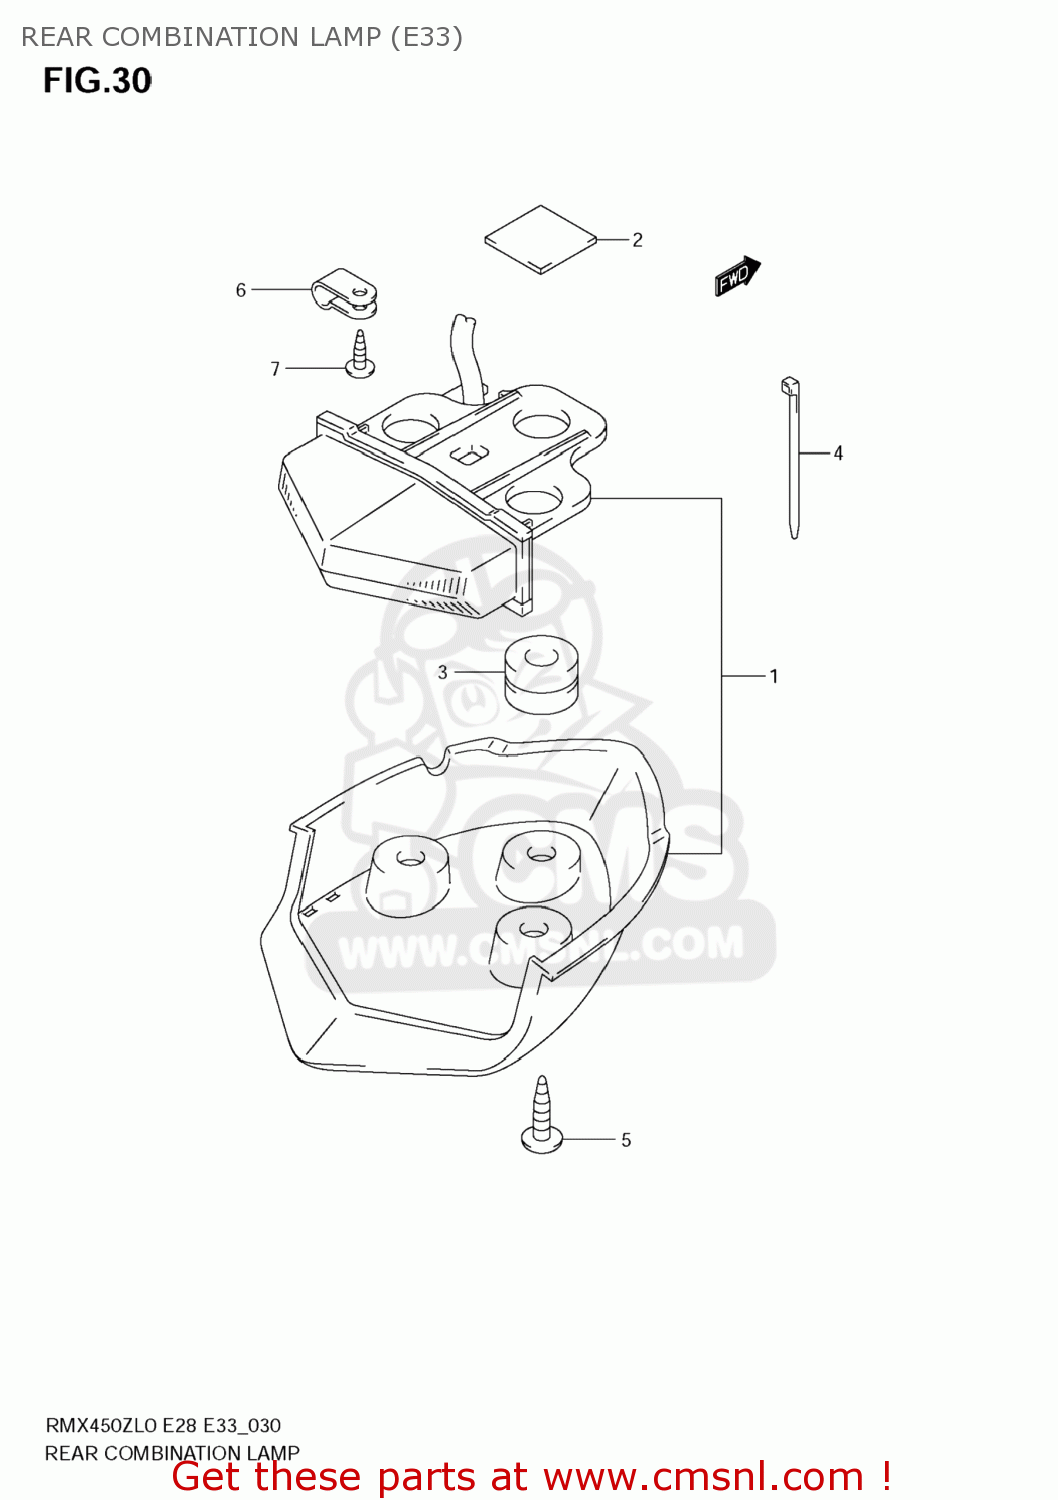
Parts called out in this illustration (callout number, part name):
1	A/LICHT UNIT.OR
2	PROTECTOR,BATTERY(30X40X1.0)
3	CUSHION
4	CLAMP(L:145)
5	SCREW
6	CLAMP
7	SCREW
